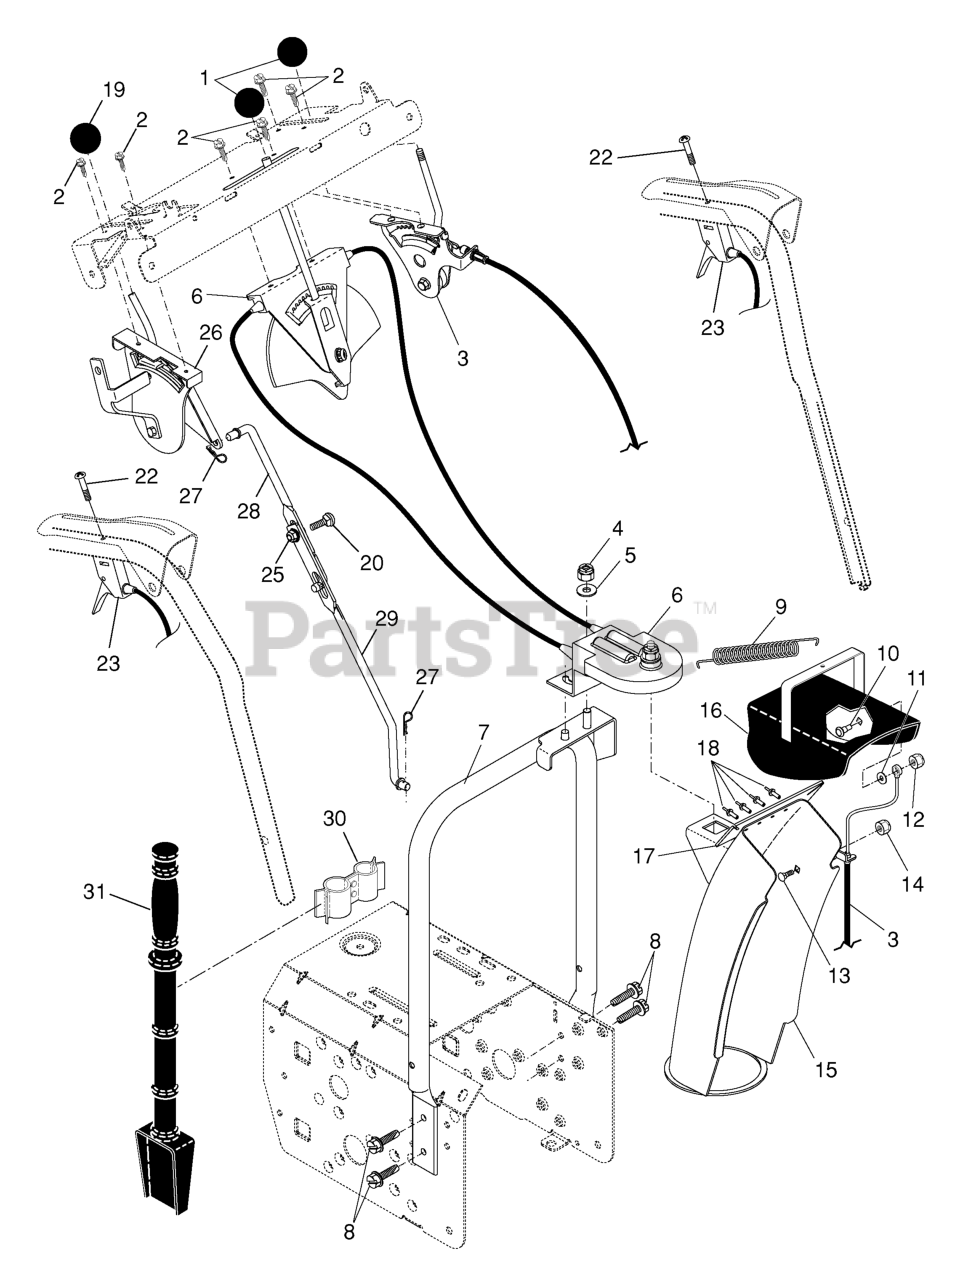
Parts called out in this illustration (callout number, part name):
1	KNOB, LEVER
2	SCREW #10-24 X 5/8
3	CONTROL ASSY, DEFLECTOR
4	NUT
5	WASHER
6	CONTROL ASSY, CHUTE ROTATER
7	SUPPORT, PIVOT
8	SELF-TAPPING SCREW 5/16-18X3/4
9	SPRING.DEFLECTOR.REM.CHUTE
10	BOLT, SHOULDER
11	WASHER, NYLON FRICTION
12	LOCKNUT.NYLOC.1/4-20
13	BOLT
14	NUT.LOCK.5/16-18
15	CHUTE ASSEMBLY
16	DEFLECTOR.WELDMENT.PNT.ORANGE
17	SEAL, DEFLECTOR
18	RIVET BLIND
19	RP KNOB, SPEED CONTROL LEVER
20	BOLT, HEX HEAD
23	STEERING.CONTROL.SNOW.BLUE
25	NUT, HEX FLANGE 5/16-18
26	HEAD ASSY SPEED
27	SPRING RETAINER
28	ROD, UPPER SPEED CONTROL
29	ROD, LOWER SPEED CONTROL.SNOW
30	CLAMP.ASM.CLEANOUT.TOOL.SNOW
31	CLEAN OUT TOOL
